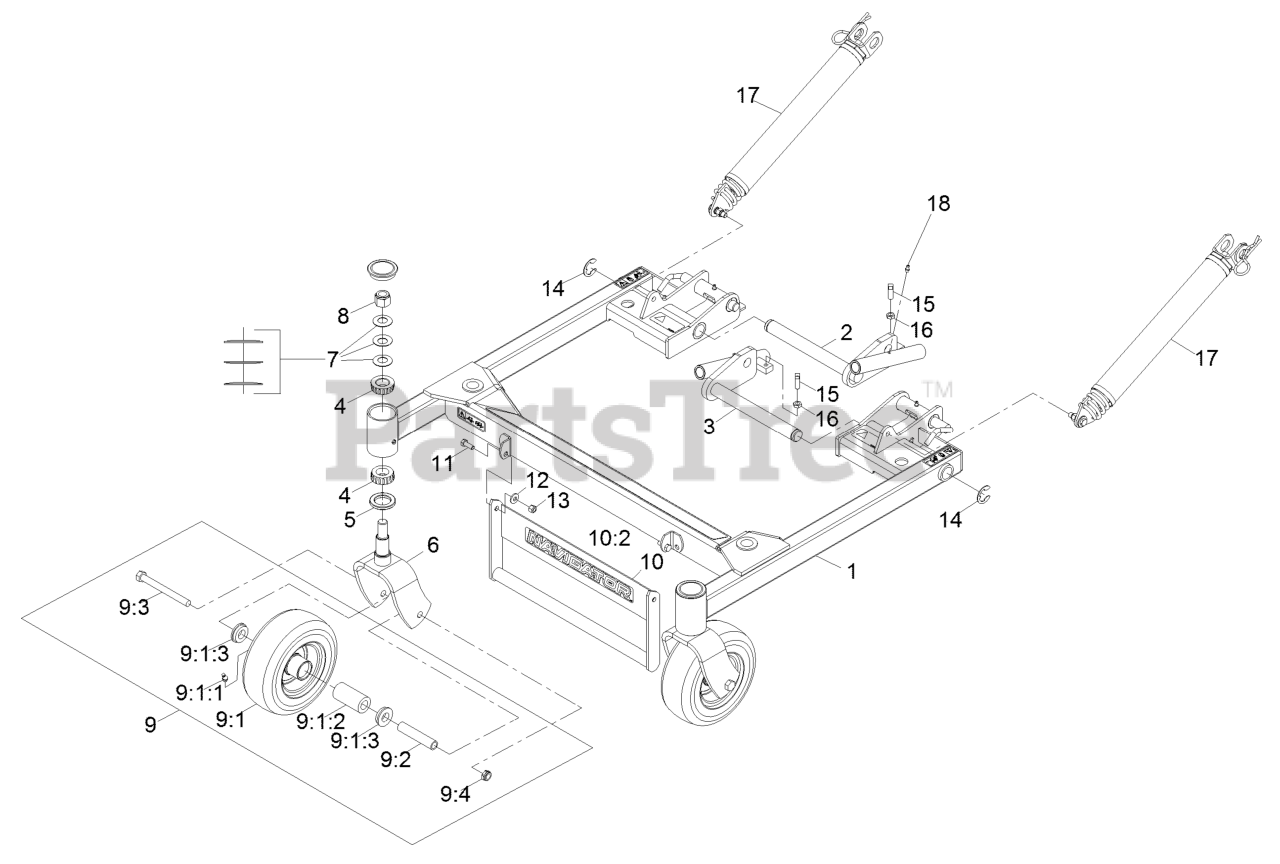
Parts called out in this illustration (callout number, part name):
1	Deck Support ASM
2	Pivot-Deck, RH
3	Pivot-Deck, LH
4	Cone-Bearing Tapered Roller
5	Seal-Grease
6	Fork-Caster
7	Washer-Spring Disc
8	Nut-Nyloc 3/4-10
9	Asm, Caster Wheel W/Axle
9:1	Asm, Wheel And Tire 8X3.00-4 Sp
9:1:1	Zerk-45deg 1/4-28
9:1:2	Bearing-Roller, Straight
9:1:3	Bushing-Flanged
9:2	Spacer-Caster, Front
9:3	Screw-HH 1/2-13 X 5
9:4	Nut-Nyloc 1/2-13 Thin
10	Asm, Deck Lift Handle W/Decal
10:2	Decal-Navigator Logo
11	Screw-HH 5/16-18 X 7/8
12	Washer-Spring Disc 5/16
13	Nut-Nyloc 5/16-18
14	Ring-Snap
15	Setscrew-SQH 3/8-16 X 1
16	Nut-Jam 3/8-16
17	Lift Assist Spring ASM
18	Zerk-1/4-28 Str
